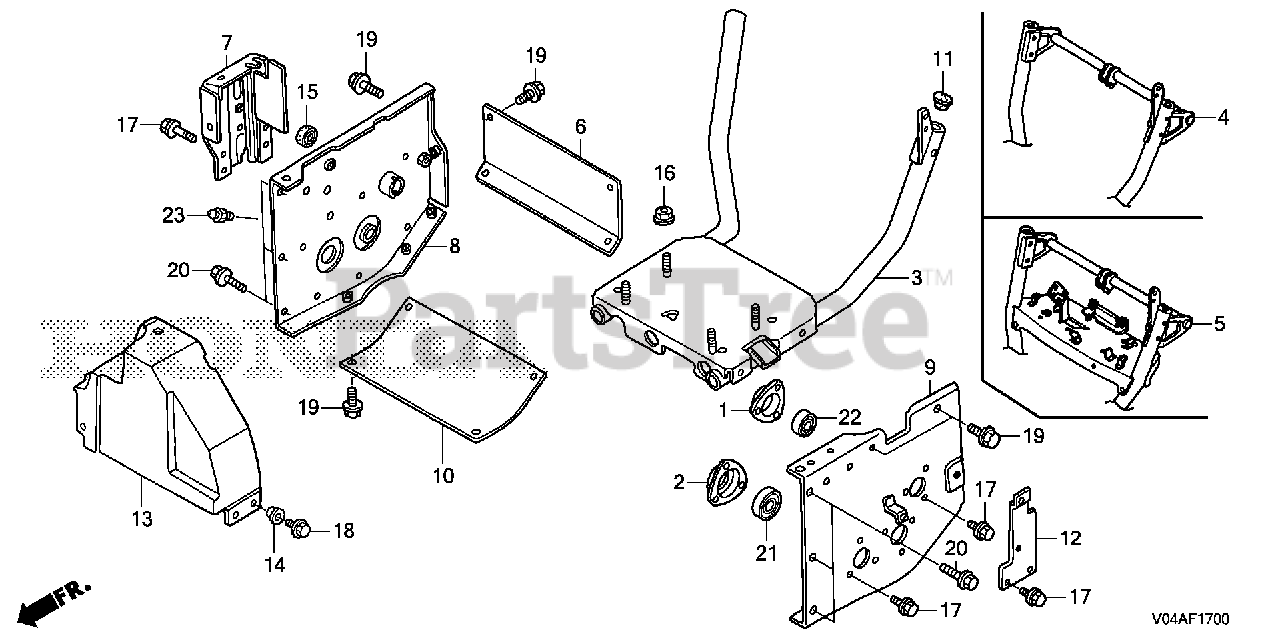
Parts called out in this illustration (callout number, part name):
1	HOLDER, BEARING
2	HOLDER, WHEEL SHAFT BEARING
3	BED, ENGINE
6	STAY, ENGINE BED
7	HOLDER, WIRE
8	STAY, R. ENGINE BED
9	STAY, L. ENGINE BED
10	STAY, ENGINE BED (B)
11	CAP, HANDLE (LOWER)
13	COVER, BELT
14	WASHER, CHAIN CASE SETTING
15	COVER, DUST (28MM)
16	NUT, FLANGE (8MM)
17	BOLT, FLANGE (6X12)
18	BOLT, FLANGE (6X14)
19	BOLT, FLANGE (8X12)
20	BOLT, FLANGE (8X16)
21	BEARING, RADIAL BALL (6004UU)
22	BEARING, RADIAL BALL (6201UU)
